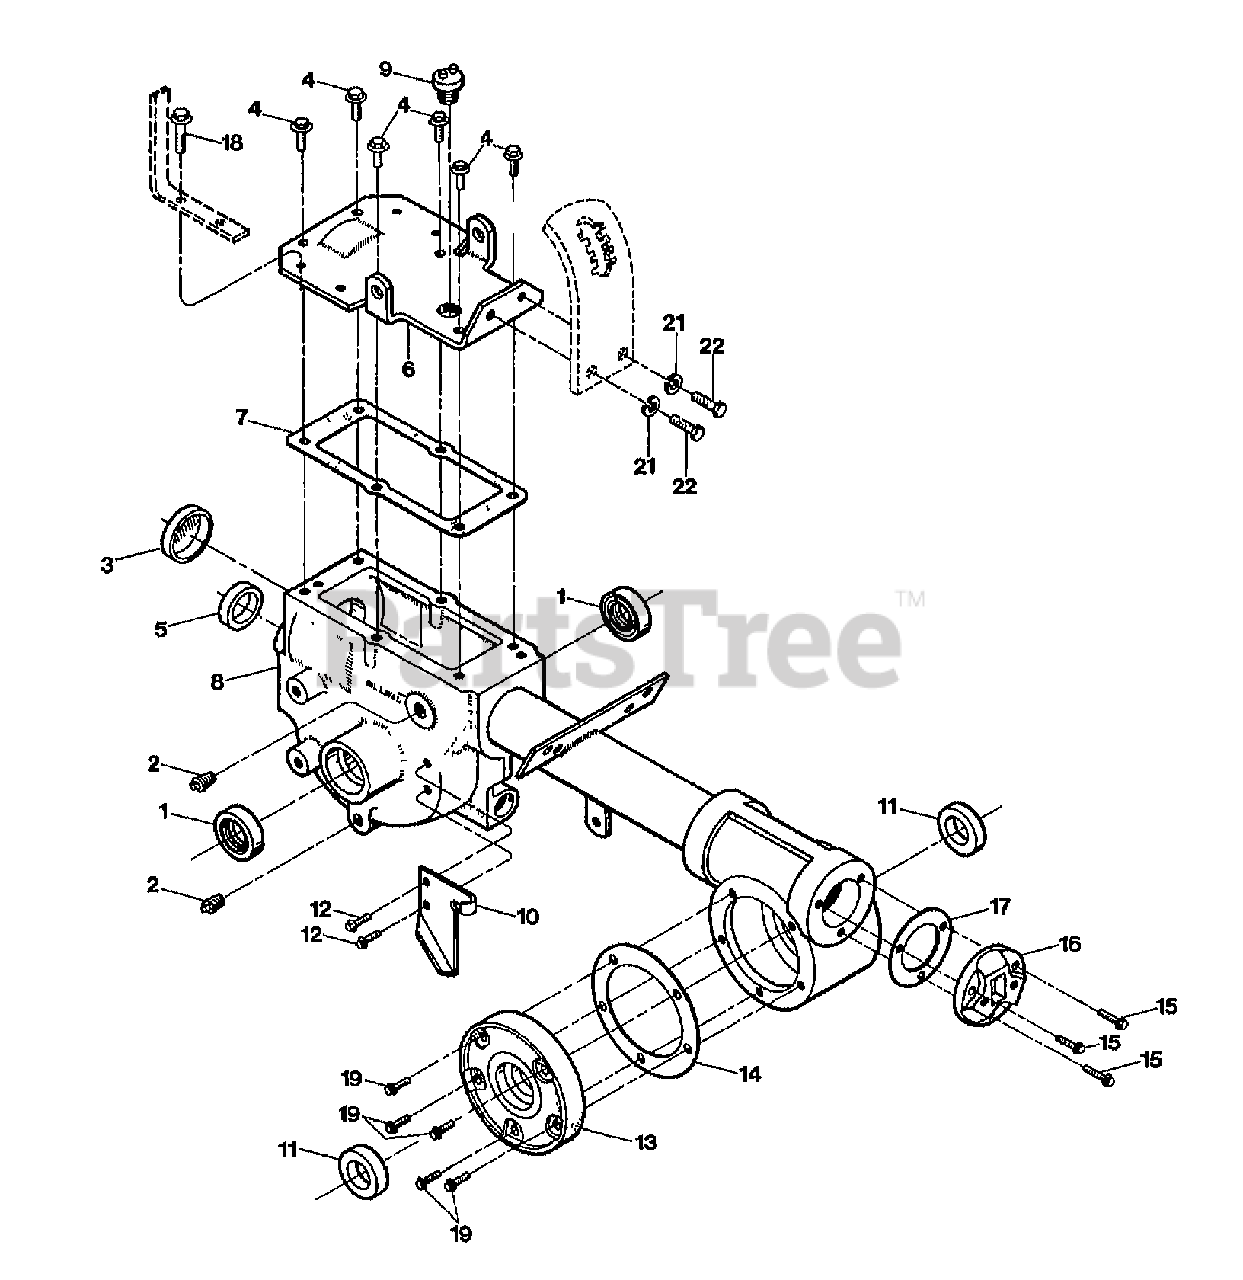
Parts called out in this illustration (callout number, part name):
1	SEAL-OIL WHEELSHAFT
2	PLUG-PIPE 1/4 NPT
3	SEAL-BORE
4	SCR-HFLK 5/16-18X.75 ZP
5	SEAL-PINION SHAFT PT/85030/00
6	KIT-COVER TRANS W/HDW - (INCL. FOUR 18 & TWO 21, 22)
7	GASKET-TRANS COVER
8	ASSM-TRANS A-UNIT P/ECHO
9	PLUG-OIL FILL 3/4-10
10	PLATE-CABLE MT PNT
11	SEAL-TILLER SHAFT
12	SCR-HFLK 5/16-18X.62 G5ZP
13	COVER-TILLER HSG MACH
14	GASKET-TILLER COVER (FITS ALL COVERS)
15	SCR-HFLK 1/4-20X.875
16	CAP-REAR #1115
17	GASKET-BRG COVER
18	SCR-HFLK 5/16-18X1.00 ZP
19	SCR-HXSKT 1/4-20X.625
21	WASHER-LK .375 @ DEPL
22	SCR-HH 3/8-16X.75 G5 ZP
